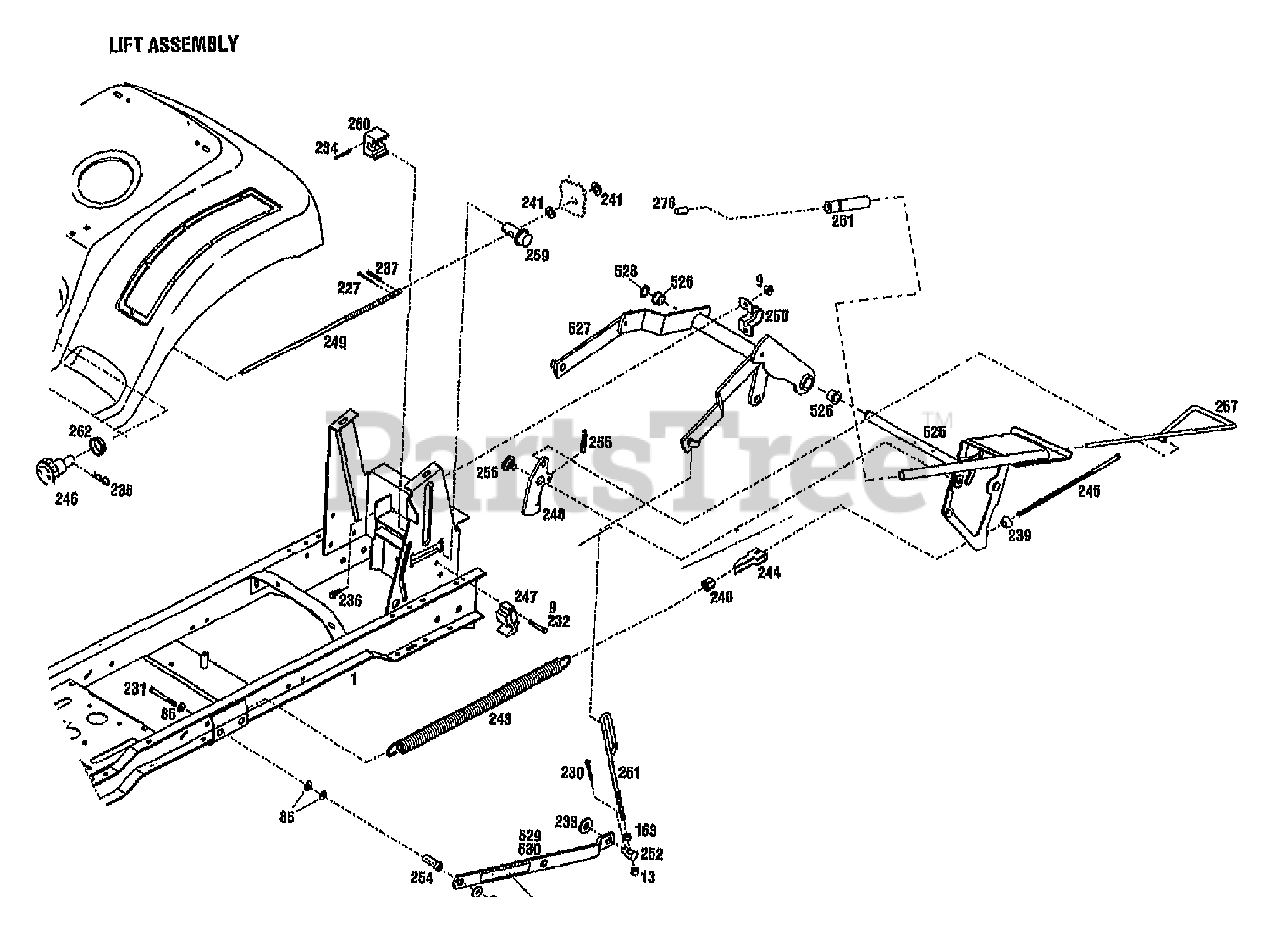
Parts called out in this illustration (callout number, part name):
1	ASSM-FRAME LTX
9	NUT-HFLK 5/16-18 ZP
13	NUT-LOCK 3/8-16
85	WASHER-FLAT 3/8 SAE
163	NUT-HEX 3/8-16 ZP
227	PIN-COTTER .125 X .75 ZP
230	PIN-COTTER .120X1.25 ZP
231	SCR-HH 3/8-16X3.0 G5 ZP
232	SCR-HH 5/16-18X1.5 G5 ZP
233	WASHER-1.305X.649X.098 ZP
234	PIN-DRIVE
235	PIN-HITCH
236	SCR-HFLK 5/16-18X.75 ZP
237	PIN-ROLL .156X1.0
239	BEARING-SPHERICAL
240	NUT-SPECIAL 5/16-18
243	SPRING-LIFT ASSIST
244	BRKT-LIFT ASSIST
245	SCR-LIFT ASSIST
246	KNOB-HEIGHT ADJUST
247	BLOCK-DETENT
249	KIT-SVC SCR HGT ADJ
250	CLAMP-LIFT
252	SWIVEL-LIFT REAR
254	SPACER
255	SPRING-EXTENSION
256	SCR-SHOULDER
259	BLOCK-HEIGHT ADJUST
260	COLLAR-HEIGHT ADJUST
261	GRIP-LIFT
262	GROMMET-SNAP BUSHING
276	BUTTON-LIFT
525	HANDLE-LIFT
528	RING-RETAINING EXT .694 ID
529	LINK-LIFT W/DECAL
530	LINK-LIFT W/DECAL
